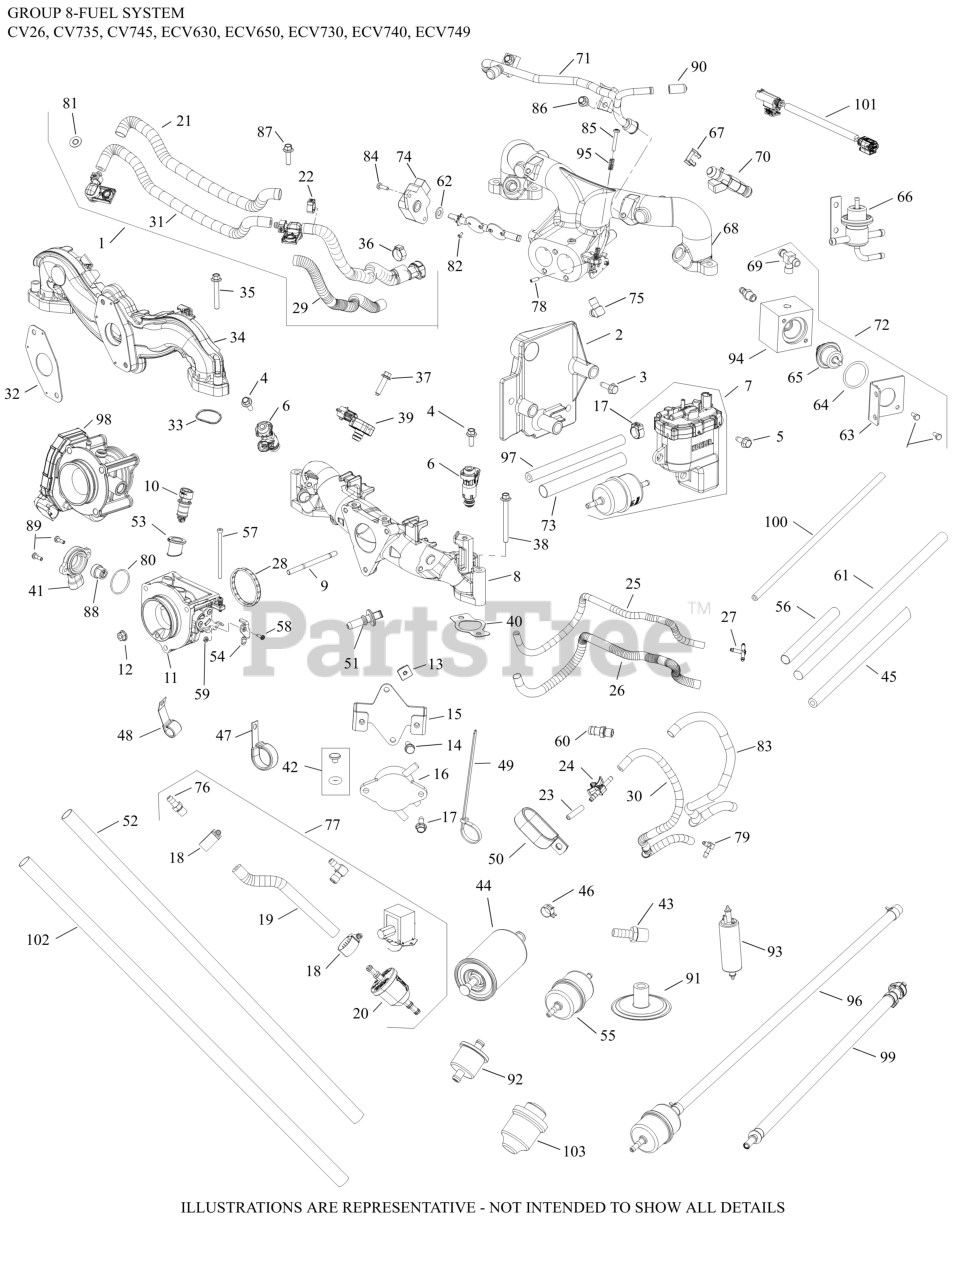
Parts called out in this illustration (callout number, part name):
1	FUEL HOSE ASSY (STRAIGHT FITTING)
2	KIT,BAFFLE, FUEL MODULE
3	SCREW, THREAD FORMING
4	SCREW, FLG M6X1.0X16
5	SCREW, FLG M6X1.0X16
6	INJECTOR, FUEL
7	KIT,FP MODULE (ECH/ECV 440,630,940)
8	KIT, MANIFOLD
9	STUD,M6X1.0X84
10	SENSOR, AIR TEMPERATURE
11	KIT, THROTTLE BODY ASSEMBLY
13	NUT, PLASTIC - BLACK
14	SCREW, TAP M6X1.7X18
15	BRACKET, FUEL PUMP MOUNTING
16	PUMP, FUEL
17	SCREW, THREAD FORMING
18	CLAMP, HOSE (KM)-USE 25 237 31-S
19	HOSE,LW PERM.FUEL 24.00"-USE 25 111 81-S
20	FILTER, FUEL
22	CLAMP, OETIKER
23	CAP, MASKING
24	CONNECTOR, EVAPORATIVE
26	SLEEVE, ANTI-ABRASION
27	TEE CONNECTOR
28	O-RING, THROTTLE BODY
30	HOSE, EVAPORATIVE (15.0)
35	SCREW, FLG M6X1.0X40
36	CLAMP, HOSE
38	SCREW, FLG M6X1.0X60
39	SENSOR, MAP
40	GASKET, INTAKE MANIFOLD-USE 24 041 79-S
41	SENSOR, THROTTLE POSITION
42	KIT, FUEL INJECTOR O-RING
46	SPRING CLAMP, HOSE
53	GROMMET, AIR TEMP SENSOR
97	HOSE, FUEL LOW-PERMEATION
